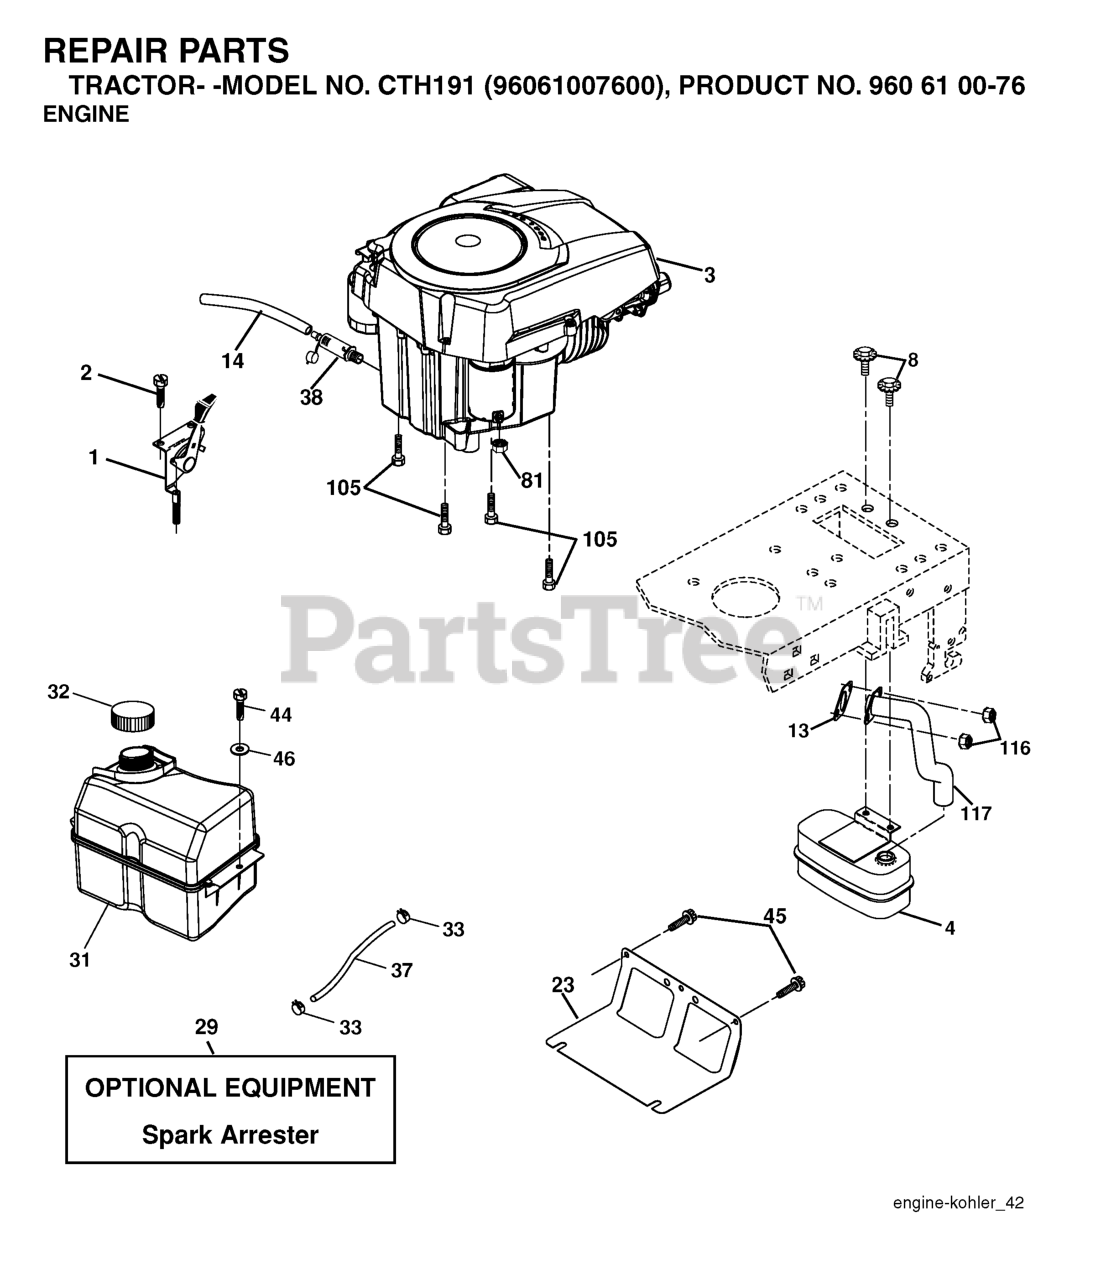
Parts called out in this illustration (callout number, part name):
1	CONTROL.THROTTLE.LT/YT
2	SCREW
4	MUFFLER.SINGLE.CYL.KOHL/B&S
8	BOLT.5/16-18UNCX3/4 W/SEMS.BLK
13	GASKET.EXHAUST.KOHLER
14	TUBE, DRAIN OIL ASM.
23	SHIELD.BROWNING.DBR.GUARD
29	KIT.SPARK ARRESTOR 794945 B&S
31	TANK FUEL
32	FUEL CAP
33	HOSE CLAMP
37	LINE.FUEL.20
38	PLUG DRAIN OIL EASY
44	SCREW HEXWSHR 1/4-20X3/4
45	SCREW, 3/8-16X3/4
81	NUT
105	SCREW 3/8-16X1
116	NUT.HEX.FLANGE.TOPLOCK
117	RP.TUBE.EXHAUST.KOHL.COURAGE
